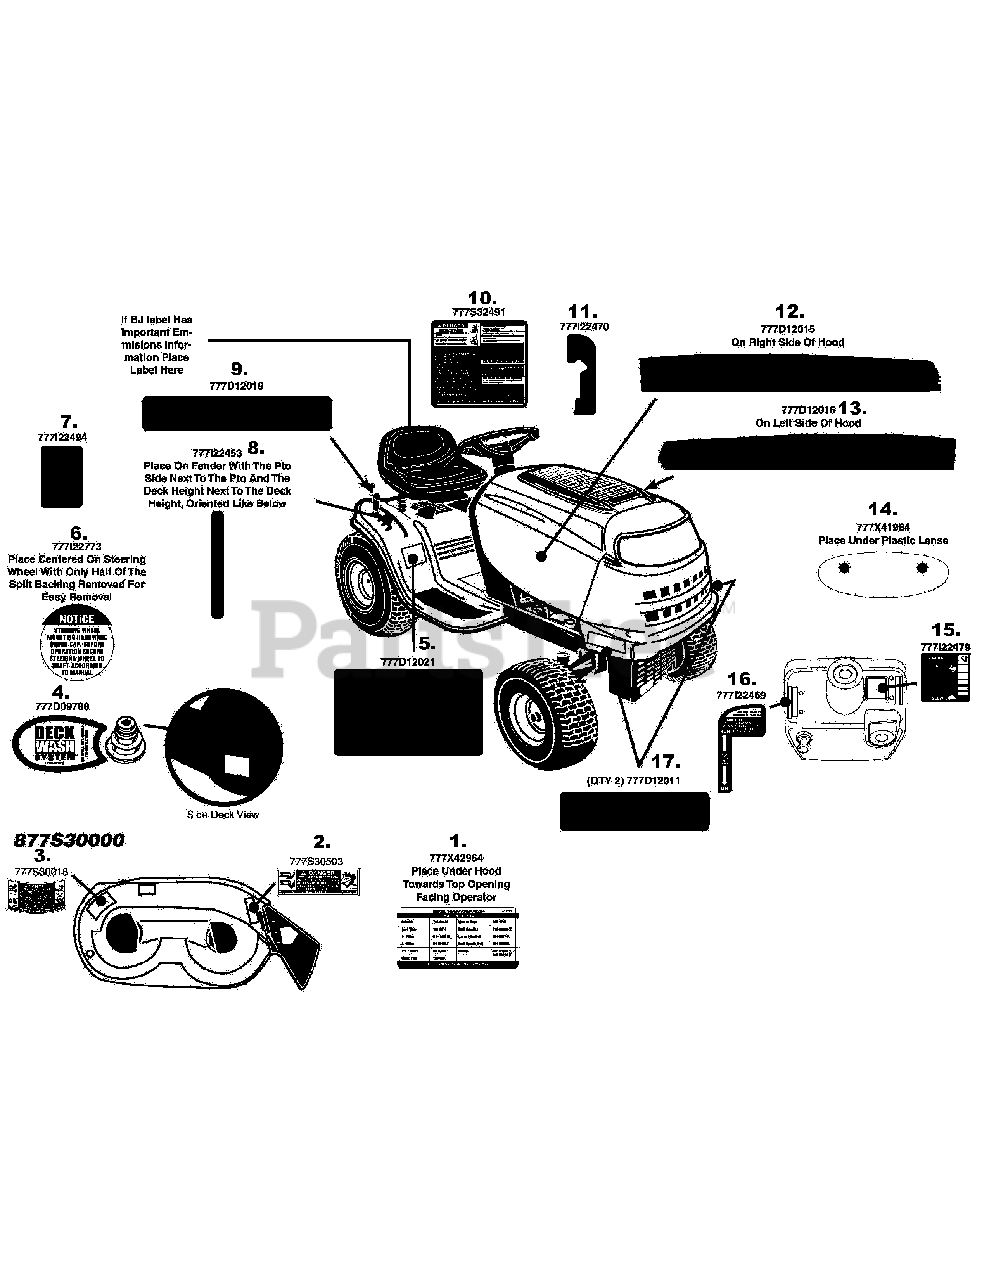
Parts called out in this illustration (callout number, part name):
1	LABEL-RIDER PARTS J795G
2	LABEL-DANGER CHUTE
3	LABEL-DECK SAFETY
4	LABEL:RIDER:WHITE
5	LABEL-RIDER FENDER42" HYDRO
6	LABEL-RIDER:SECURE WHEEL
7	LABEL:LT-5 TRANS RELEASE
8	LABEL:RIDER LT-5 FENDER
9	LABEL-RIDER REAR FENDER MTD GOLD
10	LABEL:RIDER:SAFETY LT-5
11	LABEL:RIDER:LT-5 FENDER HYDRO
12	LABEL-RIDER HOOD MTD GOLD HYDRO RH
13	LABEL-RIDER HOOD MTD GOLD HYDRO LH
14	LABEL:RIDER 1&5 STYLE GRILL
15	LABEL: RIDER LT-5 THRT/CHK
16	LABEL: RIDER LT-5 DASH HYDRO
17	LABEL-RIDER LOWER GRILLE CAST IRON
